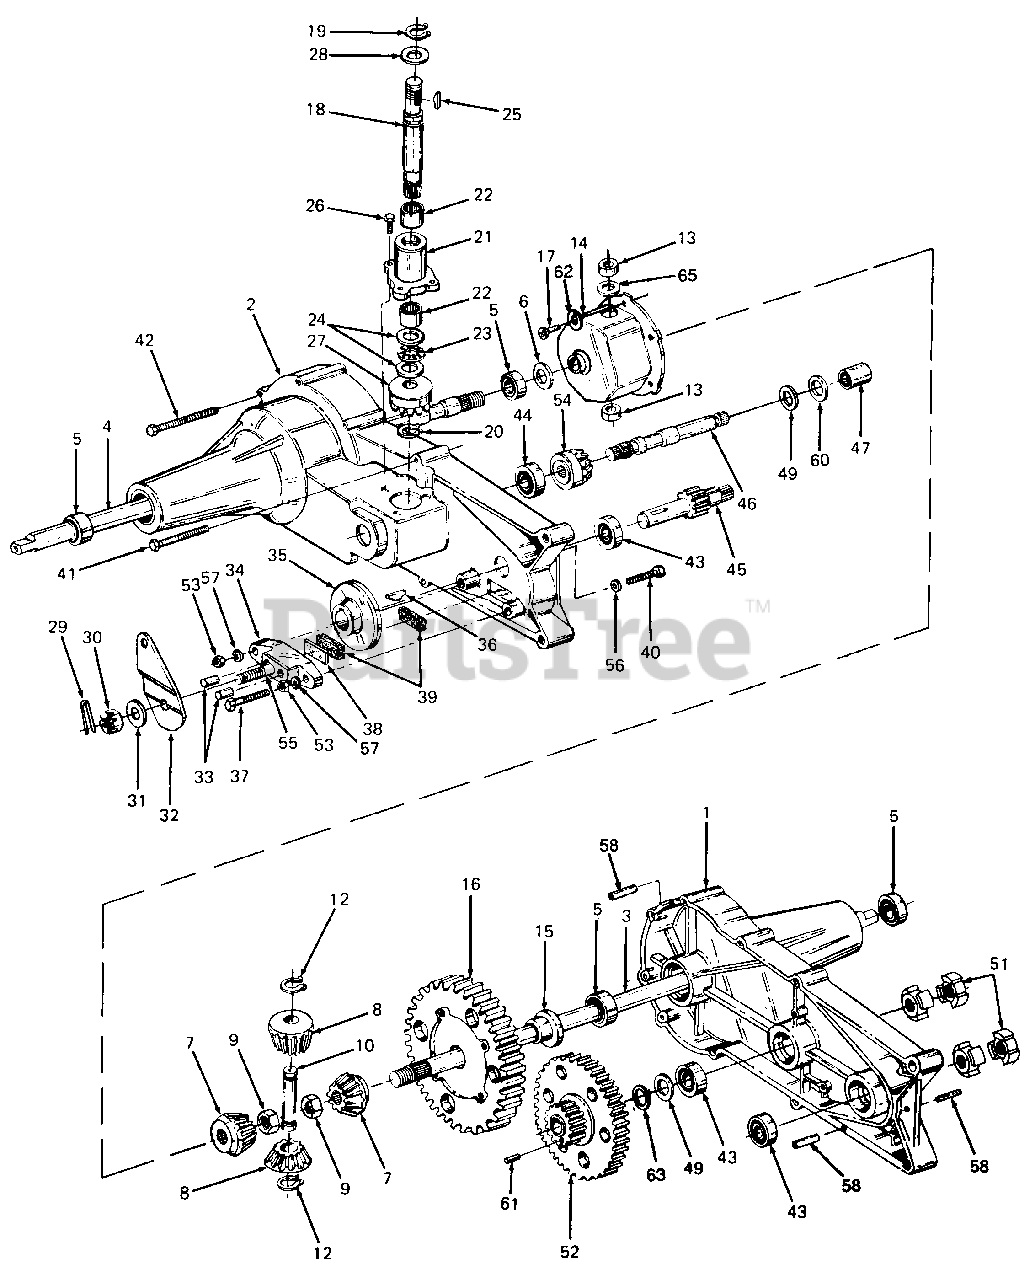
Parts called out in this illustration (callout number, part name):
1	Housing Half, L.H.
2	Housing Half, R.H.
5	Bearing, Ball
6	Washer, Flat, .76" x 1-1/8" x .306" Thk. Hdn.
7	Gear, Miter
9	Nut, Hex Jam Patch Lock, 1/2-20 0
10	Shaft, Cross
12	Ring, Snap
13	Bearing, Thrust
14	Housing Ass'y. Differential
15	Bearing, Flange, .75" I.D. x .587"
16	Gear, Differential, 72 Tooth
17	Torx Hd. AB-Tap Scr. 1/4 x .62" Lg.
18	Shaft, Input
19	Ring, Snap
20	Ring, Retaining, Ext. 7/16" Dia.
21	Bearing, Input Housing
22	Bearing, Needle, 5/8" I.D. x .50" Lg.
23	Bearing, Thrust
24	Washer, Flat, 5/8" I.D. x 1.12" O.D. x .030" Thk.
25	Key #4 Hi-Pro, 3/32" x 5/8" Dia. (Hdn.)
26	Screw, Hex Patch Lock, 1/4-20 x 3/4" Lg.
27	Gear, Input Pinion, 17 Tooth
28	Washer, Flat, .62" I.D. x 1.0" O.D. x .030" Thk.
30	Nut, Castle, 5/16-24 Thd.
31	Washer, Flat, .343" x .88n x .062" Thk.
32	Arm, Brake Actuator
33	Pin, Actuating, 5/16" Dia.
36	Key, Hi-Pro, 3/16" x 5/81' Dia.
37	Screw, Hex Patch Lock, 1/4-20 x 1 5n Lg
38	Plate, Puck
39	Puck, Brake
40	Screw, Hex Cap, 1/4-20 x 1.5" Lg.
41	Screw, Hex Self-Tap, 1/4-20 x 2 on Lg
42	Screw, Hex Self-Tap, 1/4-20 x 2.75" Lg.
43	Bearing, Ball
44	Bearing, Ball
45	Shaft, Pinion w/11 Tooth Gear
46	Shaft, Drive
47	Bearing, Needle
49	Washer, Flat, 5/8n x 1.12n x .060" Thk.
51	Coupling
52	Gear, Tooth 60 & 17
53	Nut, Hex Jam, 1/4-20 Thd.
54	Gear, Drive Pinion, 17 Tooth
55	Bolt, Square Hd. 5/16-24 Thd.
56	Washer, Flat, .265" x 938n x .12 Thk.
57	Washer, Lock, 1/4" l.D.
58	Pin, Roll, 3/16 Dia. x 50n Lg.
60	Bronze Thrust Brg. 5/8n l.D.
61	Dowel Pin 3/32" x 1/4
62	Washer, Spring Lock 1/4" l.D.
63	Seal, Grease
65	Washer, Flat, .62n I.D. x 1.0" O.D. x 020n Thk.
